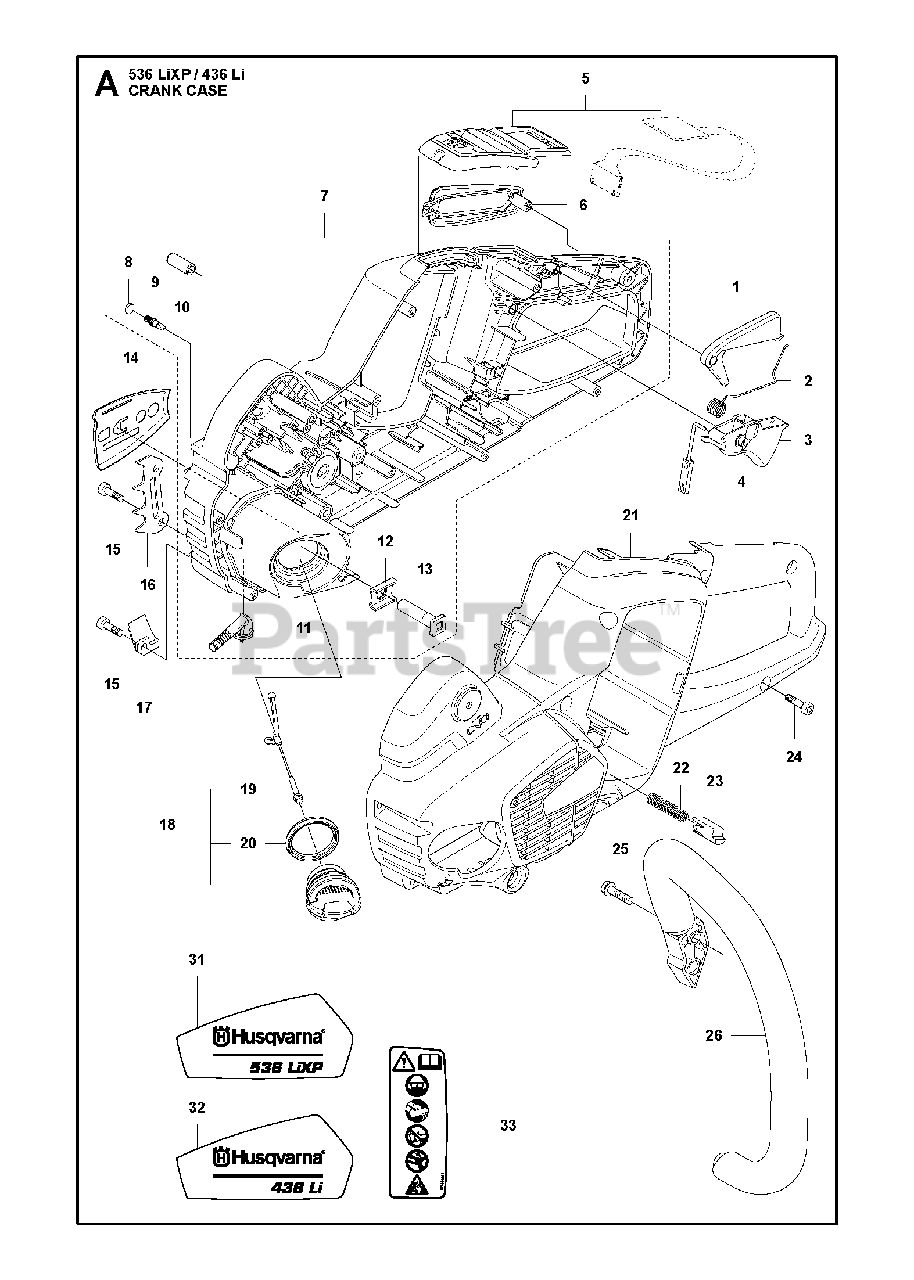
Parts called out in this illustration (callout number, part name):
1	THROTTLE LOCKOUT
3	THROTTLE CONTROL
4	THROTTLE ROD ASSY
5	COVER
6	HANDLE INSERT
7	CRANKCASE ASSY
8	PLUG
9	VALVE-CHECK (DUCKBILL)
10	GUIDE BAR LOCATING PIN
11	OIL SCREEN
12	PLATE
13	BOLT
14	CHAIN GUIDE
15	SCREW
16	INDRE BARKSTØD
17	CHAIN CATCHER
18	TANK CAP ASSY
19	TANK LOCK
20	SEALING
21	CRANKCASE
22	SPRING PUSH OUT
23	PUSH BUTTON
24	SCREW IHSCT MT4X18 10.9 ZN/FE
26	FRONT HANDLE
